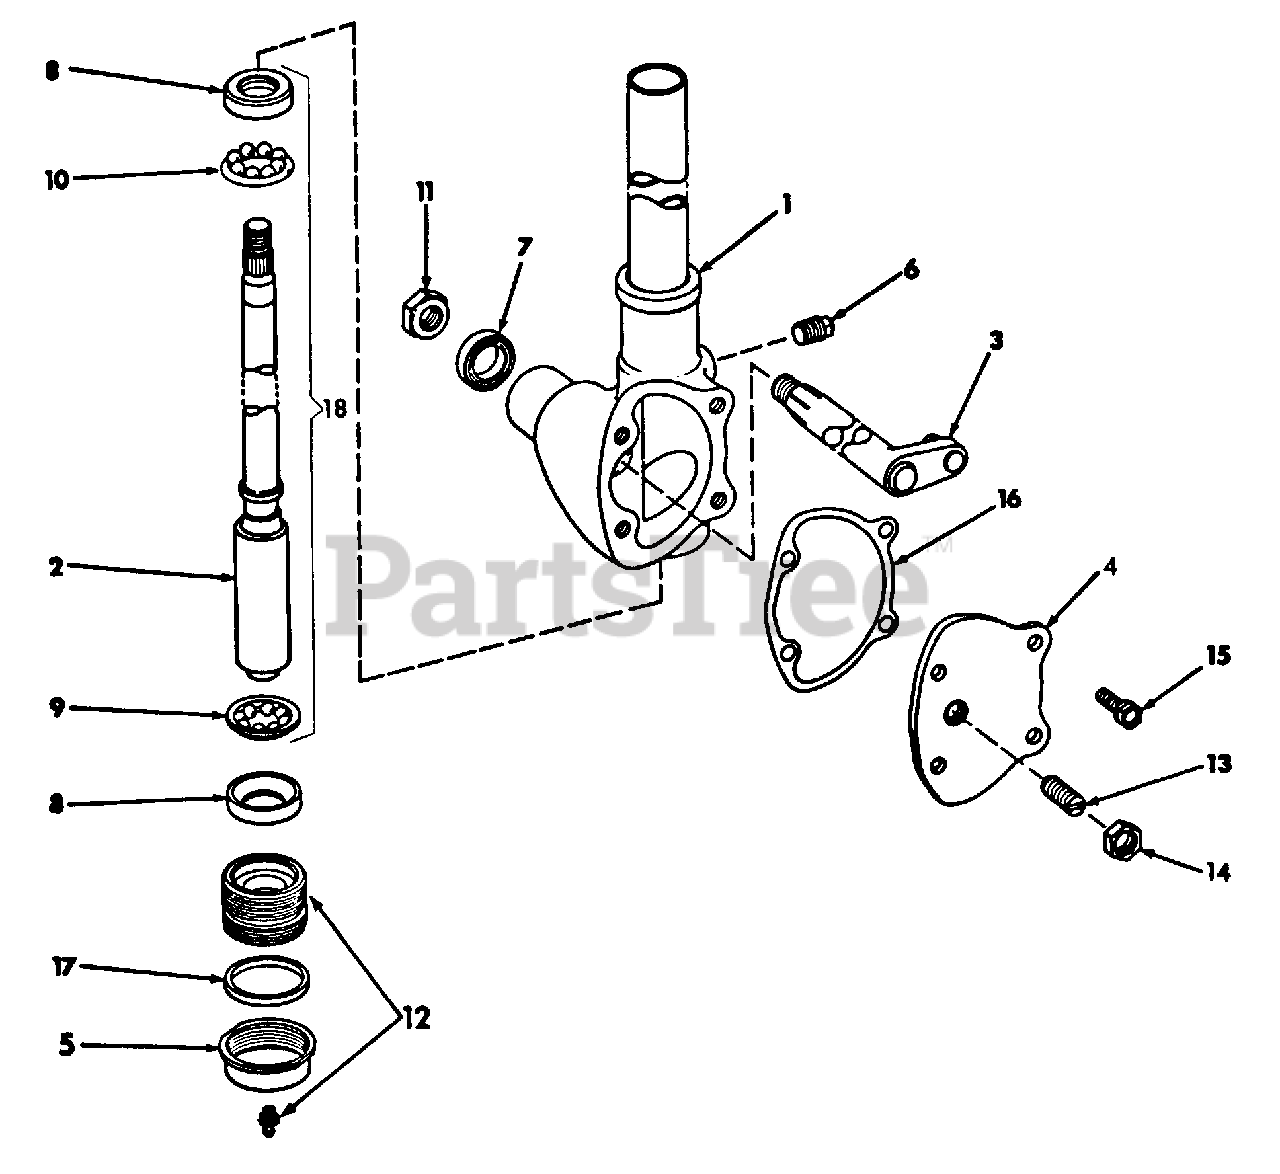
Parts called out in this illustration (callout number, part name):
1	HOUSING AND TUBE KIT
2	CAM AND TUBE ASSY
3	LEVER AND SHAFT KIT
6	PLUG, 1/4 SQ-HD PIPE
8	KIT, BALL CUP
9	RETAINER, BALL
10	RETAINER AND BALL ASSY
11	NUT, STEERING ARM
12	PLUG ASSY, LUB FITTING & ADJUSTING
13	SCREW, ADJUSTING
14	NUT ADJ, SCREW LOCK
15	BOLT W/WASHER, COVER
16	GASKET, SIDE COVER
18	CAM AND TUBE KIT
